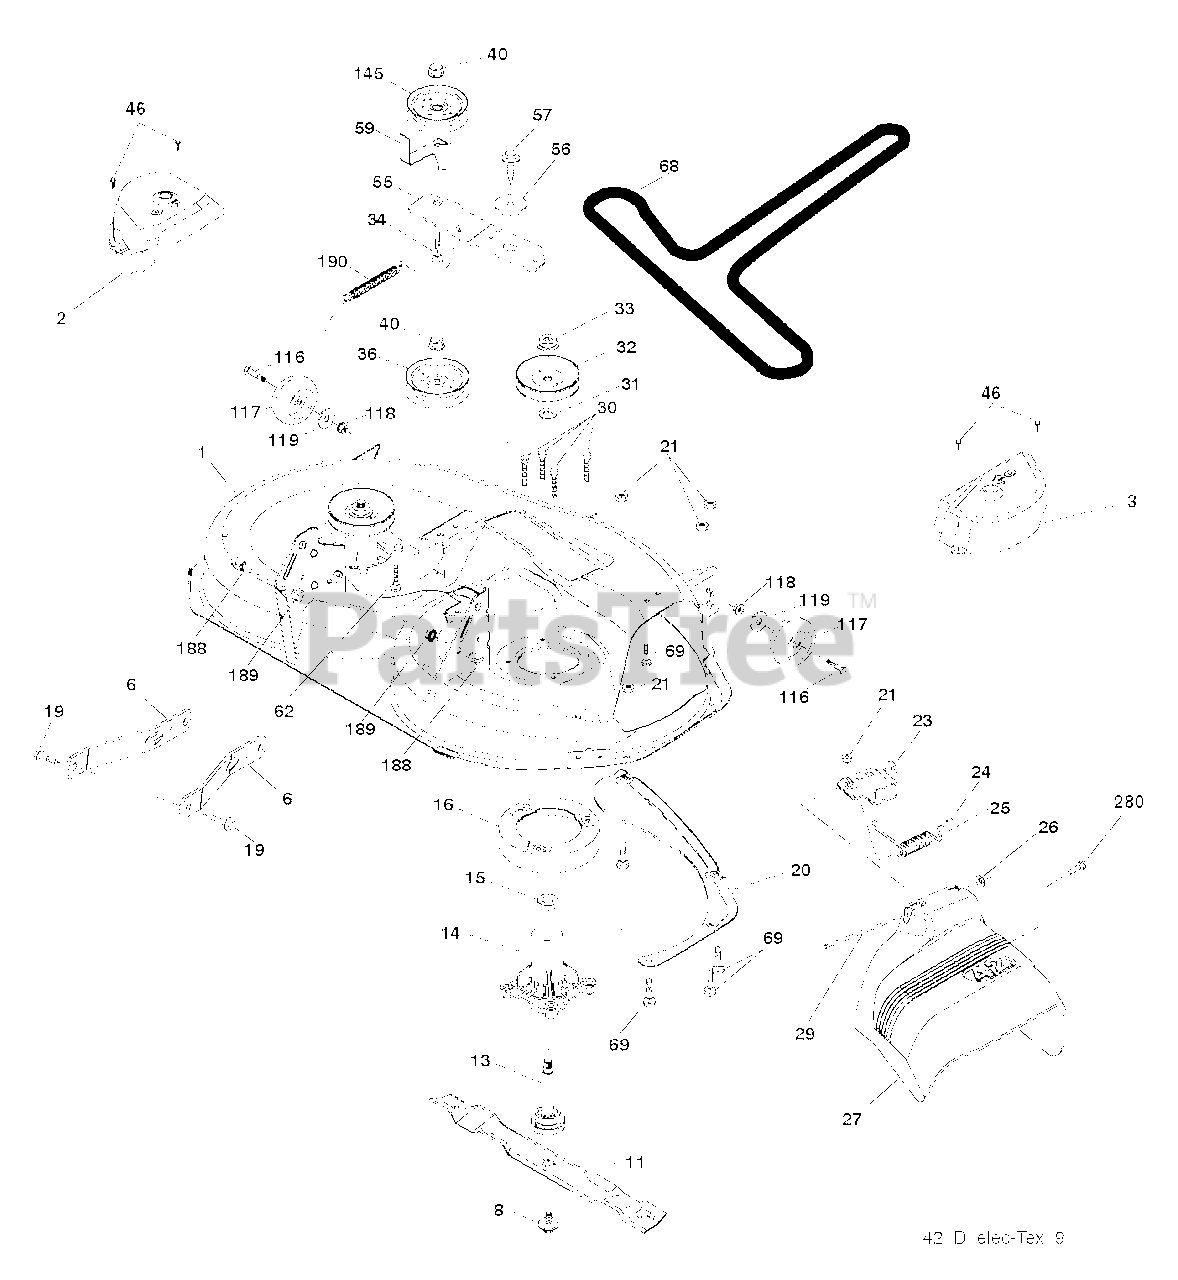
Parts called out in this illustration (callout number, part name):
1	DECK.WELDMENT.42"
6	ARM.SUSPENSION.MOWER.R
8	BOLT.WASHER.ASM.7/16-2
11	42" HI-LIFT BLADE
13	SHAFT.ASM.MDRL.N/GREASE.38
14	HOUSING MANDREL
16	STRIPPER, MWR ROUND
19	BOLT.SHOULDER
20	BAFFLE.VORTEX
21	LOCKNUT
23	BRKT.DEFLECTOR.38"2005+
24	CAP-SLEEVE LT
25	SPRING.TORSION.DEFLECT
26	NUT PUSH M
29	ROD.HINGE
30	SCREW, WASHER HEAD
31	WASHER.SPACER.MANDREL
32	PULLEY/MANDREL
33	NUT.FLANGE.LOCK.TOP
34	BOLT.3/8-16X1.50
36	PULLEY.IDLER.2006
40	NUT LOCK FLG 3/8-16 UNC
46	SCREW.1/4-20X5/8
55	IDLER.ARM
56	SPACER.RETAINER
57	SCREW 3/8-16X1
59	GUARD, BELT
62	BOLT
68	BELT V SECONDARY
69	BOLT
117	WHEEL.GAGE.HALF.SPOKED
118	LOCKNUT
119	WASHER
145	PULLEY.IDLER.48"PRIMARY
188	STUD.FASTNER.W/ANTI-ROTATE
189	NUT LOCK HEX FLANGE 5/16-18
190	SPRING.MOWER.DRIVE.ELECTRIC
280	SCREW 3/8-16X1/2
